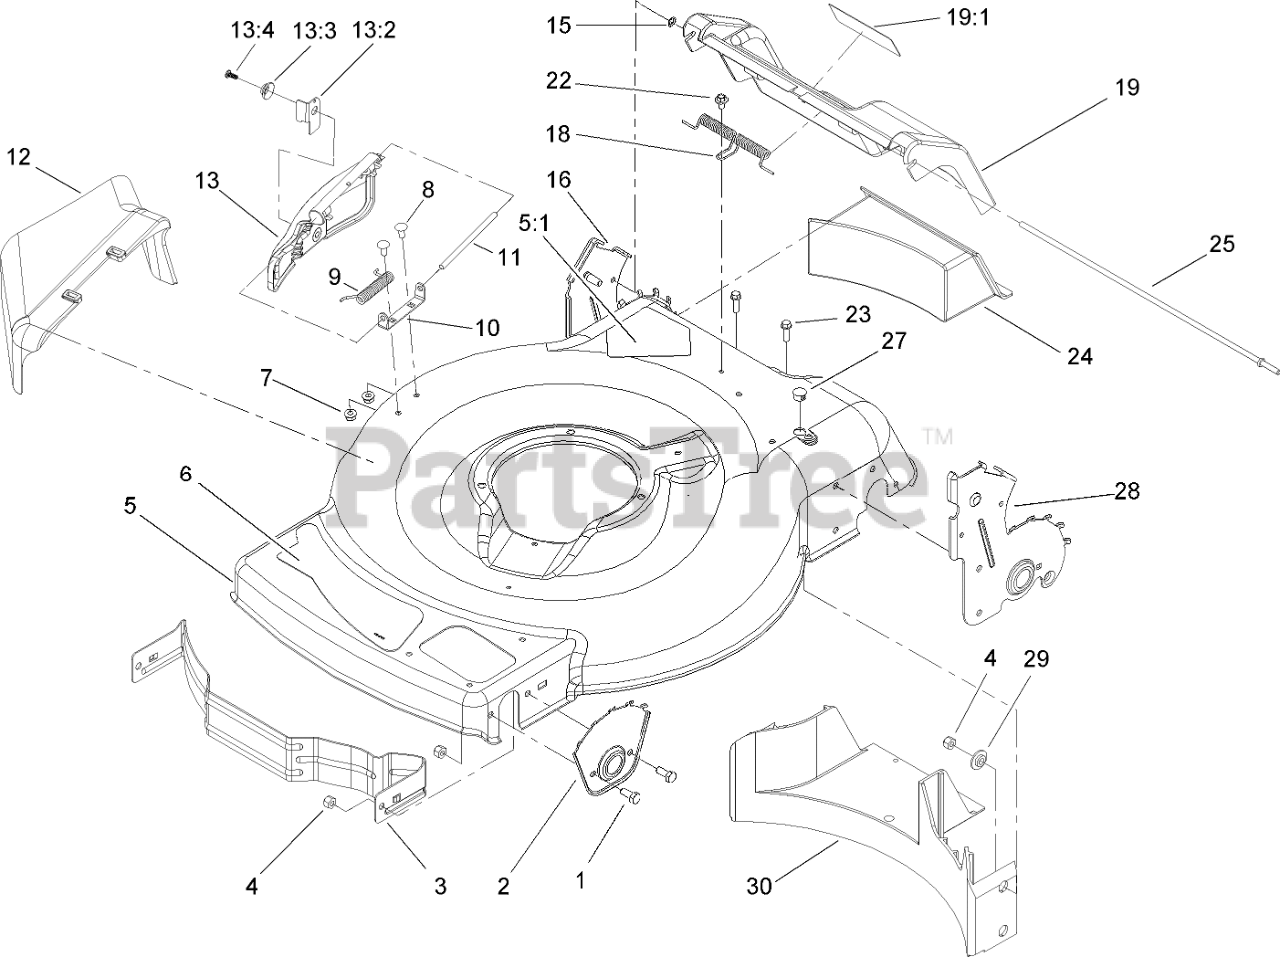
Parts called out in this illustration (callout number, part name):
1	SCREW-HH
2	Plate-HOC, Front
3	Baffle-Front
4	NUT-LOCK, NI
5	HOUSING
5:1	DECAL-DANGER
6	Decal-Deck
7	NUT-HHF
8	SCREW-CARR
9	SPRING-TORSION
10	BRACKET-COVER
11	ROD-COVER
12	CHUTE-DISCHARGE, SIDE
13	DISCHARGE DOOR ASM
13:2	LATCH-DOOR
13:3	CAP-DOOR
13:4	SCREW-PLASTITE
15	NUT-PUSH
16	RH REAR HOC PLATE ASM
18	Spring-Door, Rear
19	REAR DOOR ASM
19:1	DECAL-WARNING
22	SCREW AND WASHER ASM
23	SCREW-HWH
24	Plug-Discharge, Rear
25	Rod-Pivot, Rear Door
27	Plug-Dome
28	LH REAR HOC PLATE ASM
29	Washer-Stepped
30	Baffle-Rear
